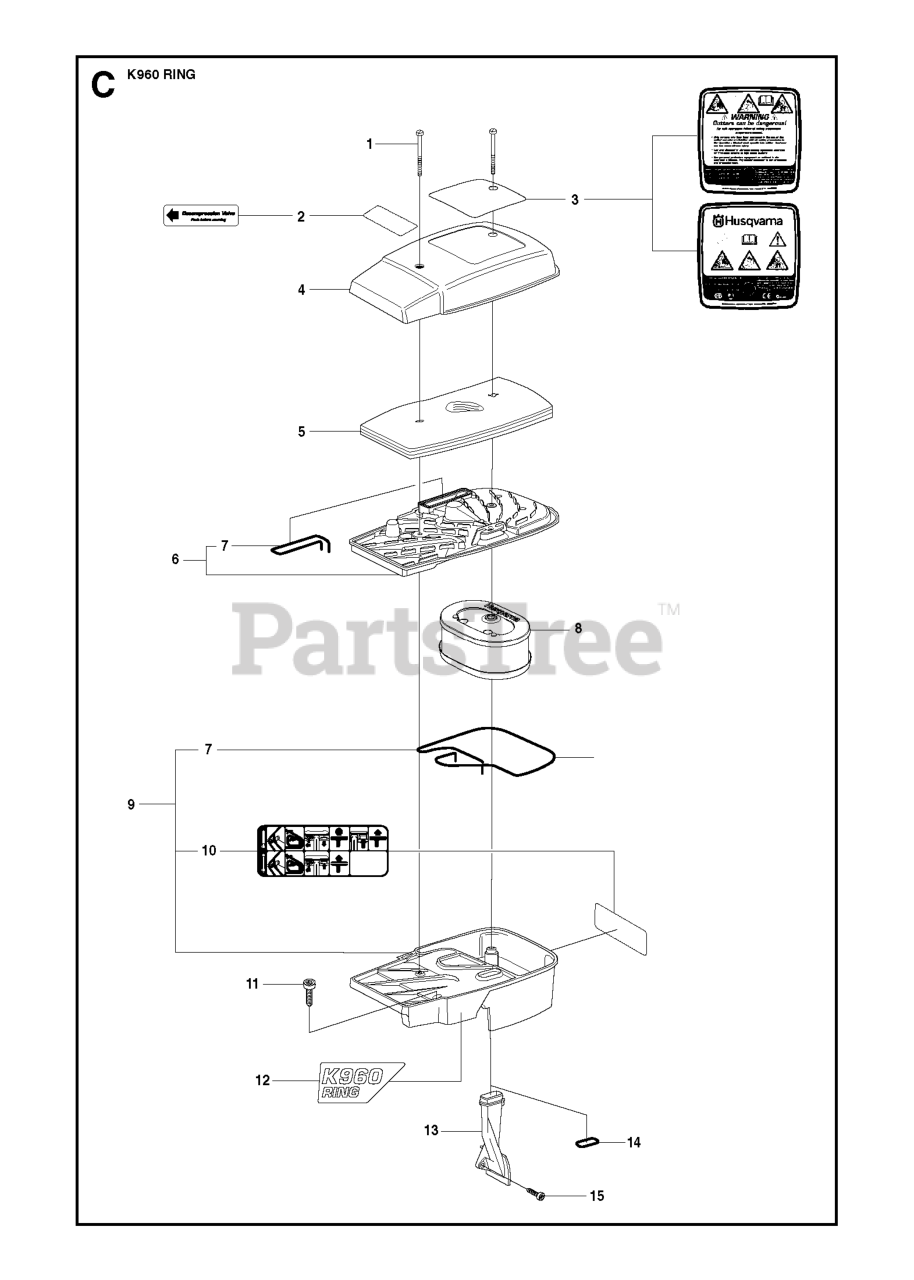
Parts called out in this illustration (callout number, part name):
2	LABEL DECOMP. LEFT
3	LABEL EPA2 USA
3	LABEL EPA2
4	AIR FILTER COVER
5	AIR FILTER
6	FILTER BOTTOM
7	SEAL
8	AIR FILTER
9	CYLINDER COVER ASSY
20	RP AIR FILTER PAPER
